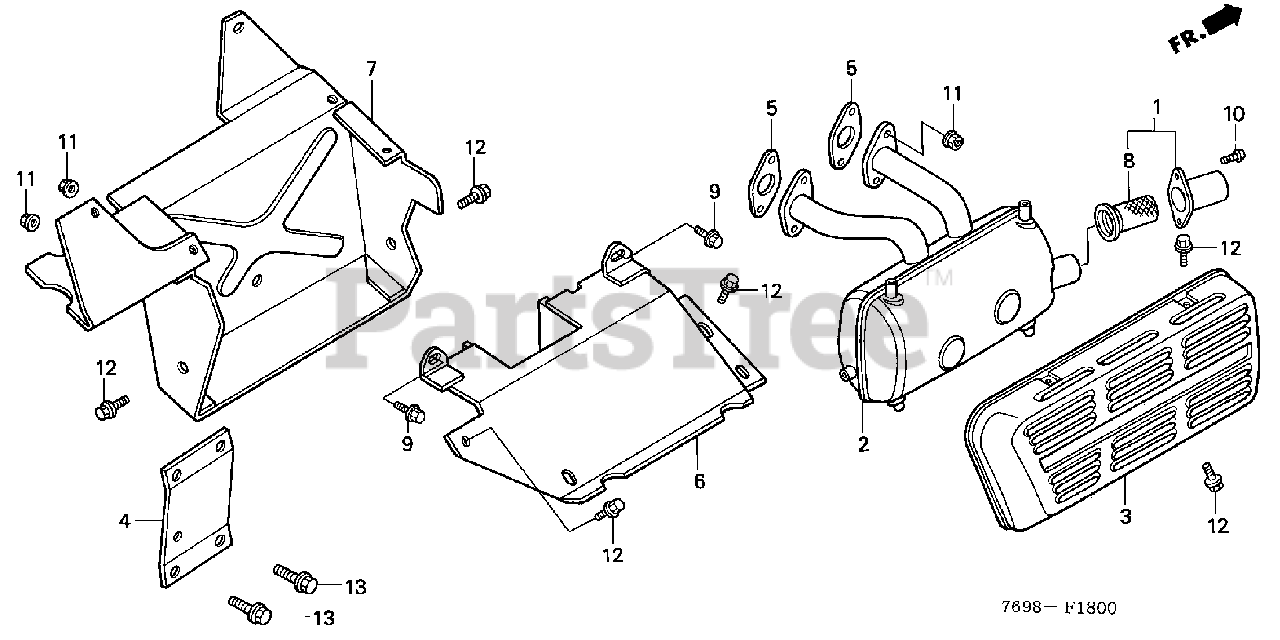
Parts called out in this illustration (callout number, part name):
1	CAP SET, ARRESTER
2	MUFFLER
2	MUFFLER (ARRESTER)
3	PROTECTOR, MUFFLER
4	BRACKET, MUFFLER
5	GASKET, EX. PIPE
6	PROTECTOR, HEAT (UPPER)
7	PROTECTOR, HEAT (LOWER)
8	ARRESTER, SPARK
9	BOLT, FLANGE (6X12) (CT200)
10	SCREW, PAN (5X8)
11	NUT, FLANGE (8MM)
12	BOLT, FLANGE (6X10)
13	BOLT, FLANGE (8X16)
